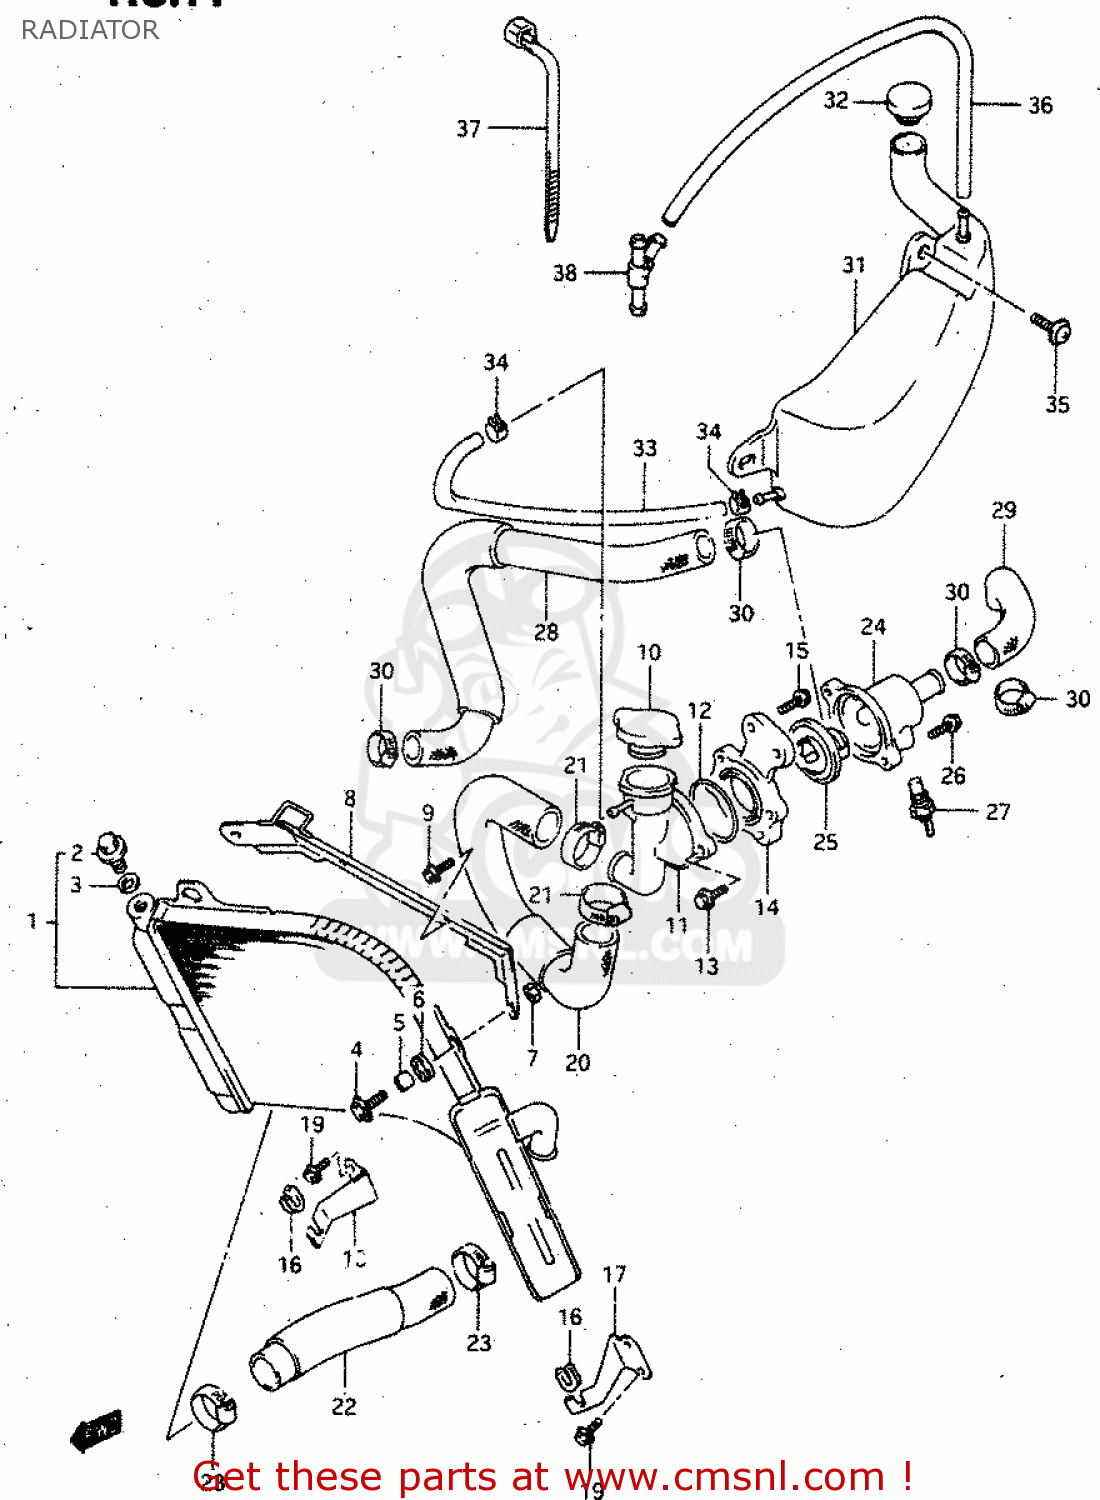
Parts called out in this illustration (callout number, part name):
1	RADIATOR ASSY,WATER
2	PLUG
3	GASKET
4	BOLT 6X20
5	SPACER (6.8X10X10)
6	CUSHION
7	NUT
8	BRACKET,RADIATOR UPR
9	BOLT
10	CAP,RADIATOR
11	CONDUCTION,RADIATOR
12	O RING(D:2.4,ID:43.2)
13	BOLT
14	BRACKET,CONDUCTION
15	BOLT
16	CUSHION,OIL COOLER NO.2
17	BRACKET,RADIATOR UPR,L
18	BRACKET,RADIATOR LWR,R
19	BOLT
20	HOSE,RADIATOR INLET
21	CLAMP
22	HOSE,RADIATOR OUTLET
23	CLAMP
24	CONNECTOR,THERMOSTAT INLET
25	THERMOSTAT,WATER
26	BOLT
27	GAUGE,WATER,TM
28	HOSE,RADIATOR JOINT NO.1
29	HOSE,RADIATOR JOINT NO.2
30	CLAMP
31	TANK ASSY, RESERVOIR
32	CAP,RESERVOIR TANK
33	HOSE,RESERVOIR TANK INLET
34	CLIP
35	SCREW(6X20)
36	HOSE(5X9X600)
37	CLAMP
38	3 WAY
